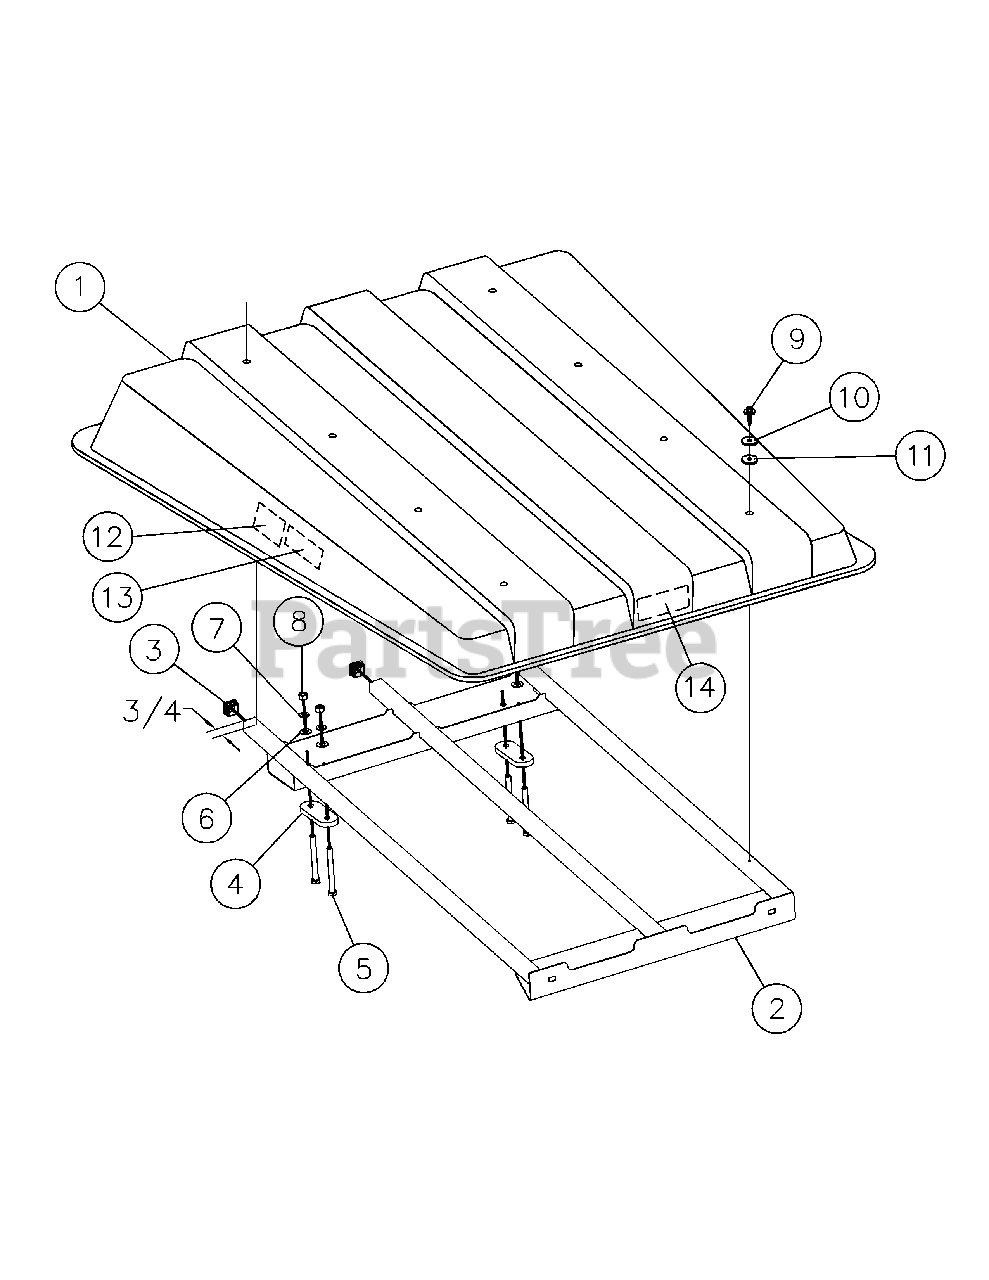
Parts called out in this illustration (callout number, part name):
1	Canopy Roof Panel
2	Canopy Rood Frame
3	Canopy Frame End Cap
4	Canopy Mount Plate
5	HHCS, 3/8-16 x 3.50
6	Washer, Flat 3/8
7	Washer, Lock 3/8
9	Screw, 1/4-14 x 1
10	Fender Washer 5/16
11	Rubber Washer 5/16
